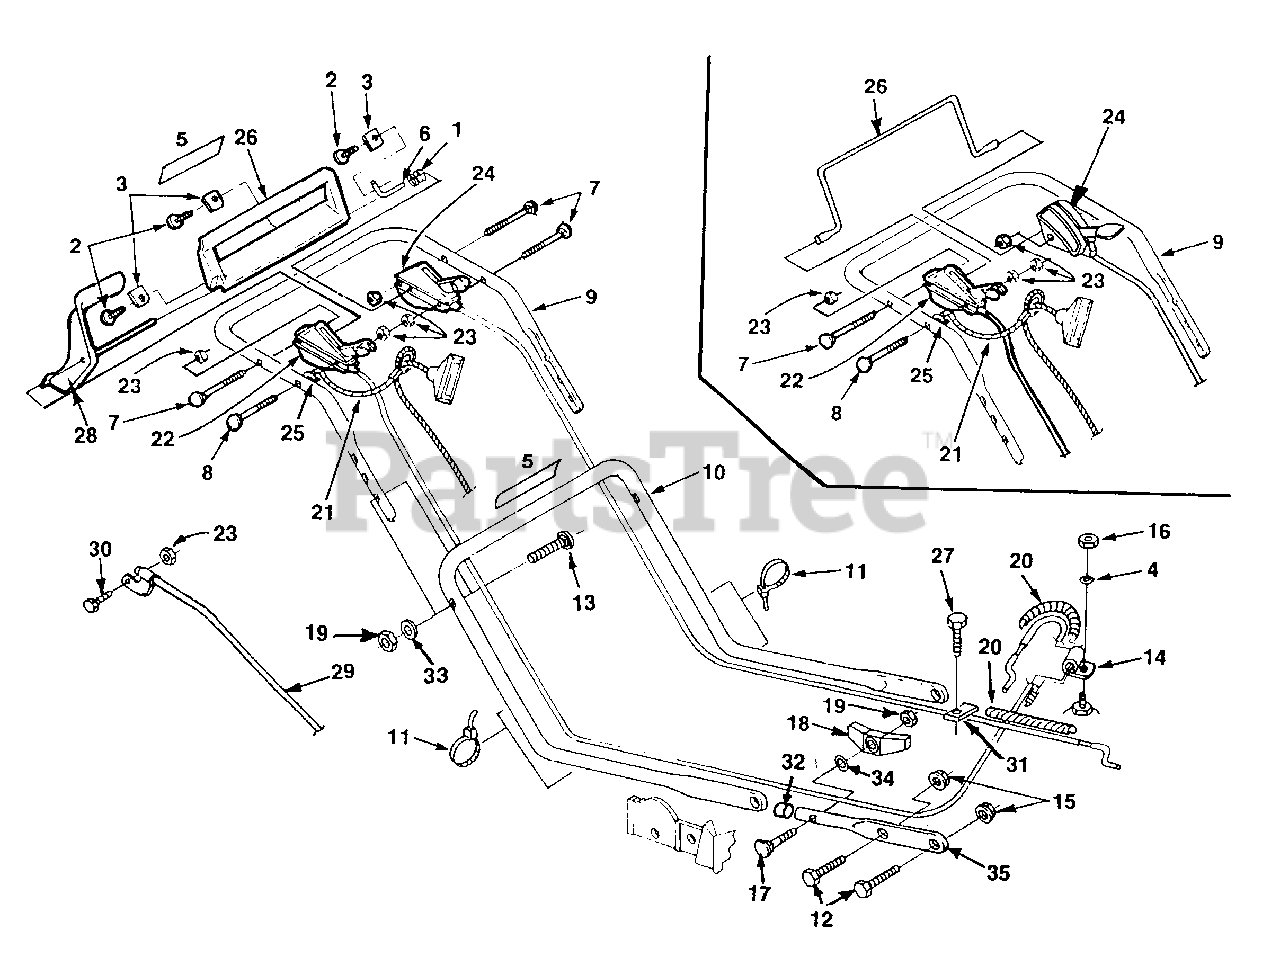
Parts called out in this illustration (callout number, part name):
1	SPRING - Compression
2	SCREW - 1/4-10 x 5/8"
3	CLAMP - Pivot shaft
4	WASHER - Lock 1/4"
5	DECAL - Starting Instr.
6	SHAFT - Pivot
7	BOLT - Sq. nk.
8	BOLT - Sq. nk.
9	HANDLE - Upper
10	HANDLE - Lower
11	CABLE - Tie
12	BOLT - Hex 5/16-18 x 1
13	SCREW - 5/16 - 18 x 1 1/2"
15	NUT - Flange 5/16 - 18
16	NUT - Hex 1/4 - 20
17	BOLT - Handle joining
18	KNOB - Handle
19	NUT - Hex 5/16 - 18
20	COVER - Cable
21	GRIP Restraint
23	NUT - Lock 1/4 - 20
24	CONTROL - Throttle
26	BAIL - Brake control
27	SCREW - Hex 1/4 - 20 x 5/8"
28	TRACTION LEVER ASSY.
29	CABLE - Traction control
30	SCREW - 1/4 - 20 x 1 1/2
32	PLUG - Cap
33	WASHER - Lock 5/16 - 18
34	WASHER - Flat 5/16
35	Stub-Handle mtg.
